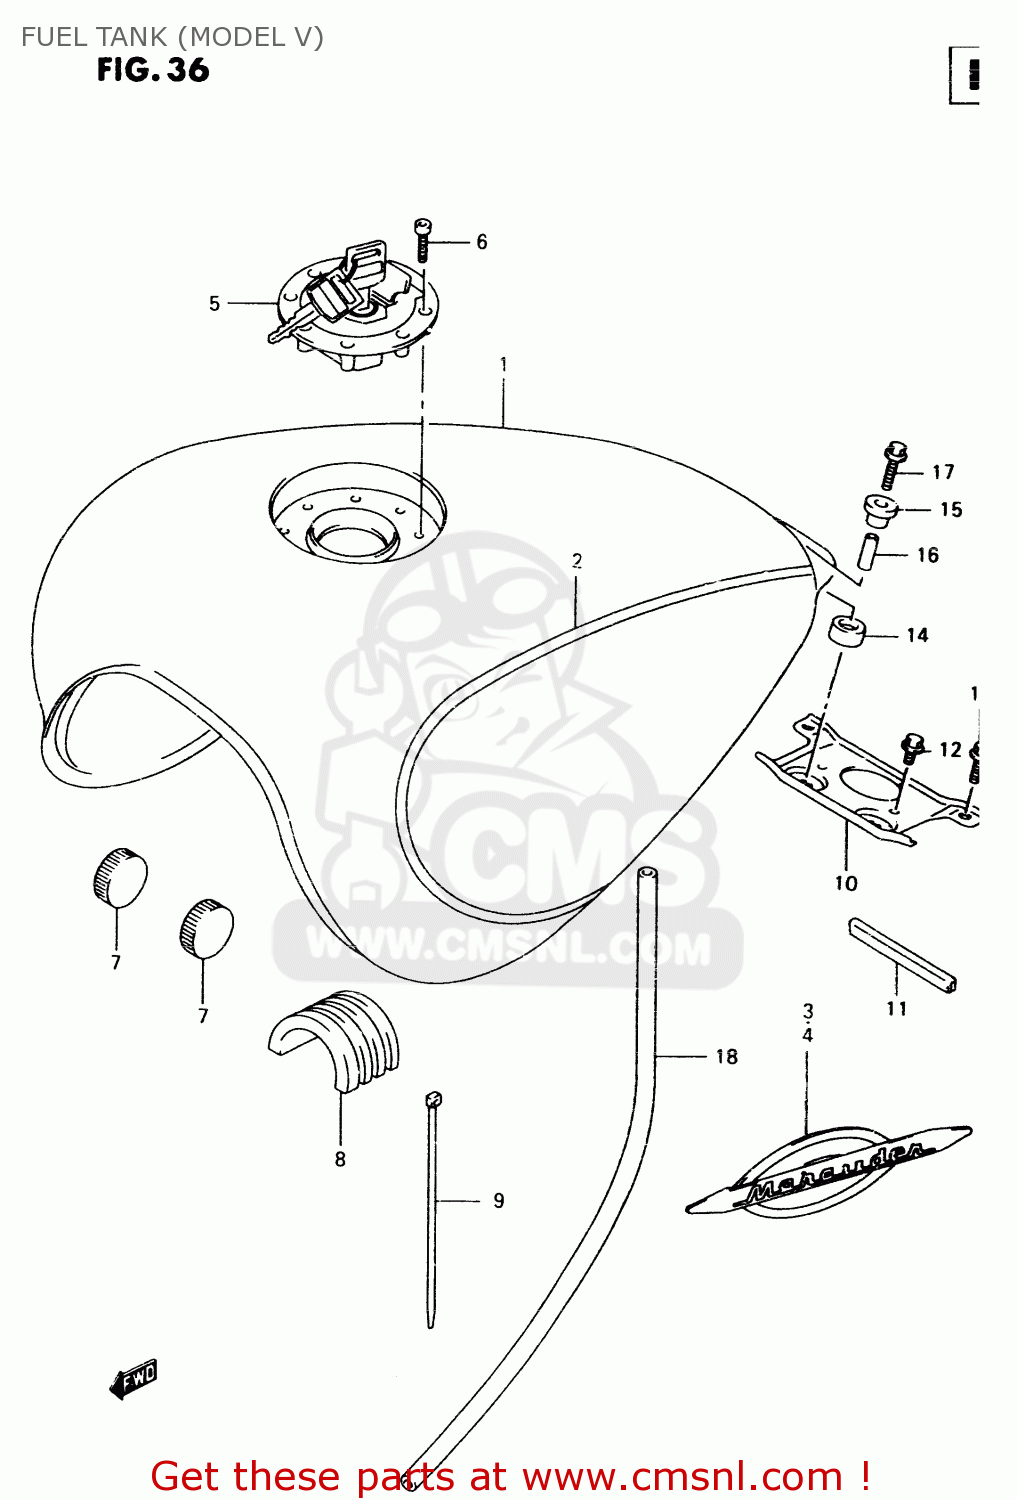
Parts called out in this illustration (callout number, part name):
1	TANK ASSY,FUEL
2	TAPE SET,FUEL TANK
3	EMBLEM,FUEL TANK,R
4	EMBLEM,FUEL TANK,L
5	CAP SET,FUEL TANK
6	BOLT(5X20)
7	CUSHION
8	CUSHION,FUEL TANK UPR
9	CLAMP(L:250)
10	BRACKET,FUEL TANK,REAR
11	PROTECTOR
12	BOLT
13	BOLT
14	CUSHION,FUEL TANK RR NO.2
15	CUSHION
16	SPACER(6.5X10.5X22.5)
17	BOLT
18	HOSE,DRAIN
